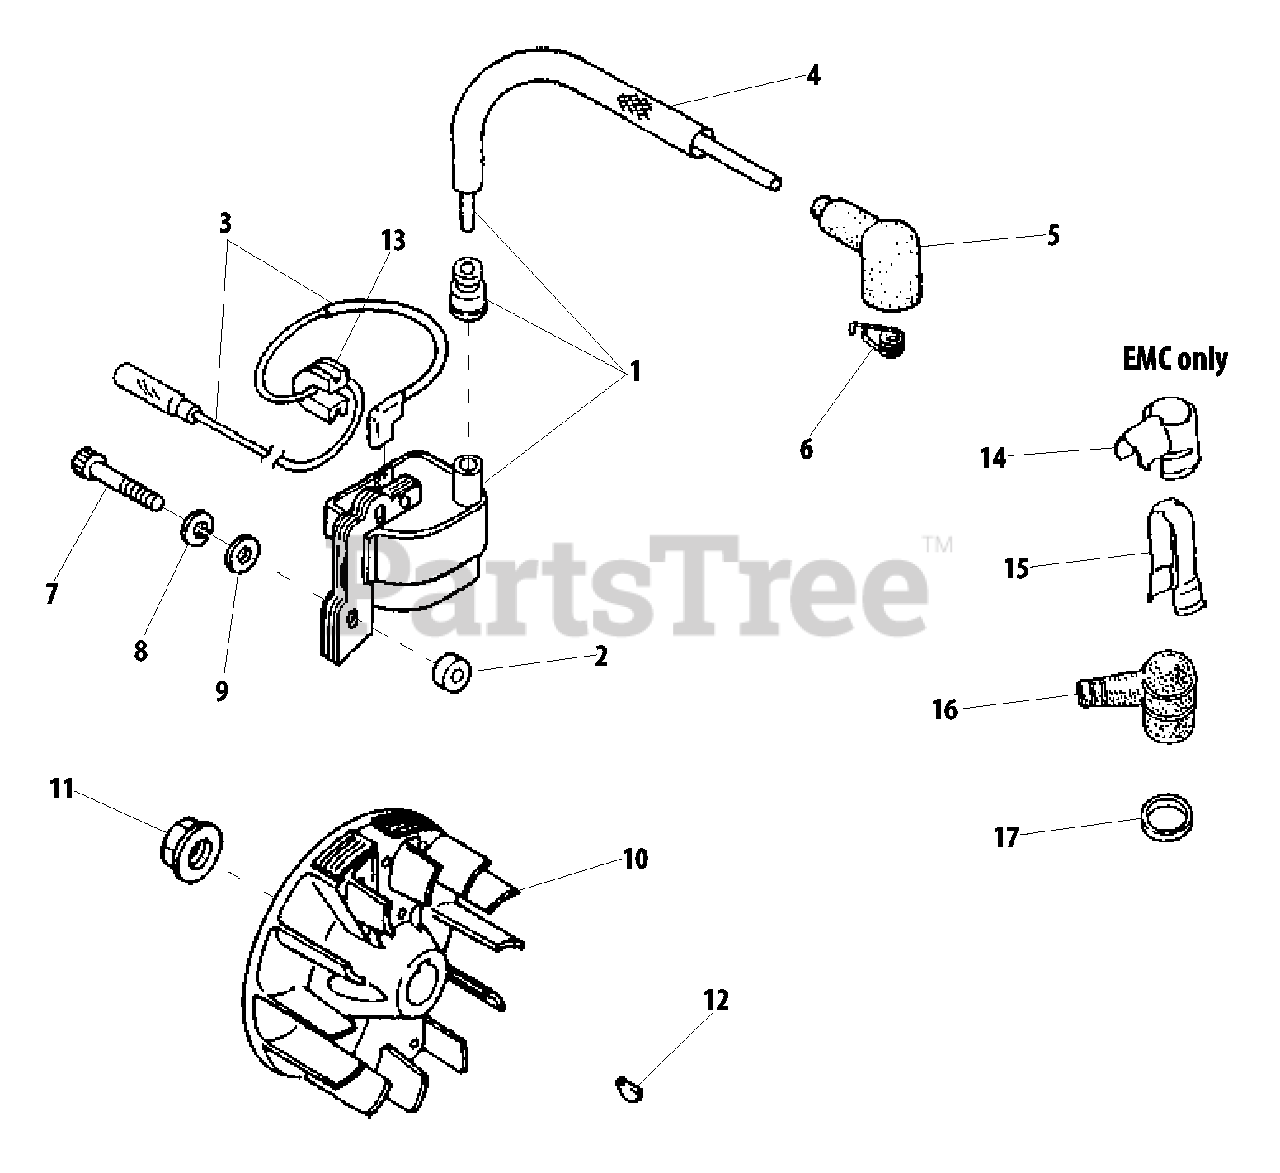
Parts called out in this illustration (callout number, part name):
1	COIL ASSY, IGNITION
2	INSULATOR 4.2×11×6
3	LEAD - IGNITION
4	TUBE, INSULATOR
5	CAP, SPARK PLUG
6	TERMINAL, SPARK PLUG
7	BOLT
8	WASHER, SPRING 4 MM
9	WASHER 4 MM
10	FLYWHEEL
11	NUT M8
12	KEY, WOODRUFF 3×10
13	GROMMET, LEAD
14	COVER, CAP
15	SHIELD
16	CAP, SPARK PLUG
17	SEAL, SPARK PLUG
